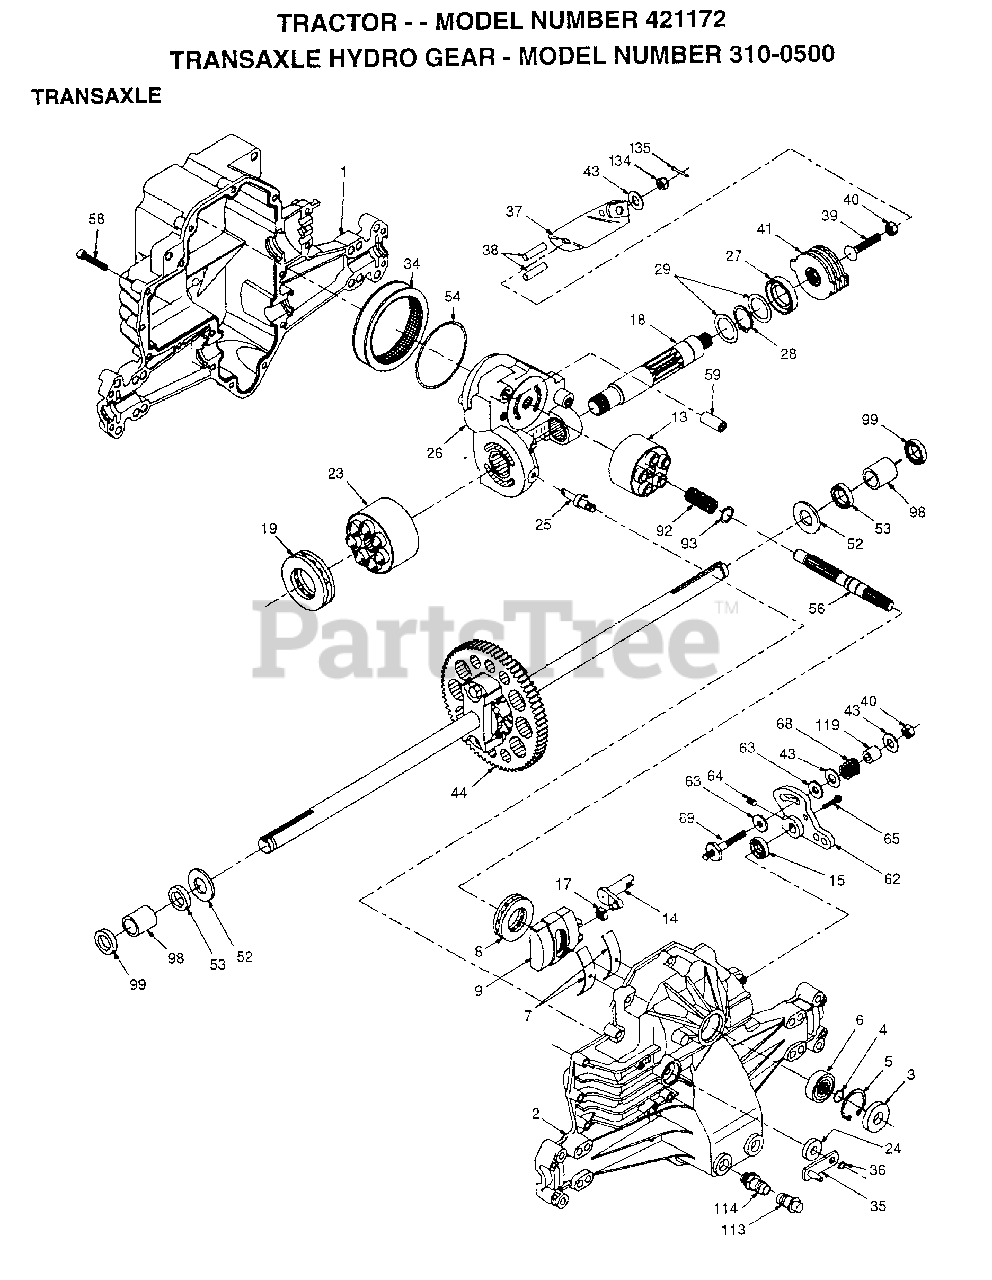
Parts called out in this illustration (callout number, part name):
1	HOUSING.L.44863RM
2	HOUSING.UPR.70122
3	SEAL.9008000-0128
4	RING.RET.2003016.
5	RING.RET.2003052.
6	BEARING.(50552)42X68X16
7	CRADLE- 2003023.
8	BEARING.THU.50551
9	SWASHPLT.2003087.
13	BLOCK.CLYN.70079.
14	ARM.TRUN.2003005.
15	SEAL.9008000-0126
17	GUIDE.2000015.
18	SHAFT.MOTOR.50449
19	BEARING.THU.50552
23	BLOCK.CYLIN.70082
24	SEAL.LIP.45074
25	ACTUATOR.2003555
26	KIT.CEN.SEC.70250
27	SEAL.LIP.45075
28	RING RETAIN 50007
29	WASHER.44872
30	PLATE.BYP.2003554
34	ELEMENT.OIL.44964
35	ARM.BYPASS.50270
36	RING.RETAIN.44870
37	ARM.ACTUAT.23710
38	PIN.ACTUAT.44891
39	BOLT.50316
40	NUT.LOCK.HX.50317
41	KIT.BRAKE.70135
43	WASHER HYD 44130
44	DIFFERNTIAL.70126
52	WASHER.HYD.44875
53	SEAL.HYDRO.45076
56	SHAFT.INPUT.50005
58	BOLT.1/4-20.44876
59	PIN.HYDRO.50002
62	ARM.CONTROL.50254
63	PUCK.DAMPER.50281
64	SCREW.SET.50018.
68	SPRING.HYD.50277
69	STUD.5/16-24.DANA
92	SPRING.2003014.
93	WASHER.2003017
98	BEARING.SLV.50137
99	SEAL.WIPER.50941
113	CAP.VENT.70109
114	O-RING.ASM.70110
119	SPACER.HYD.50278
134	NUT.CAS.HYD.44142
135	PIN.COT.HYD.44101
140	NUT.HEX.50269
319	SPRING.COMP.50431
